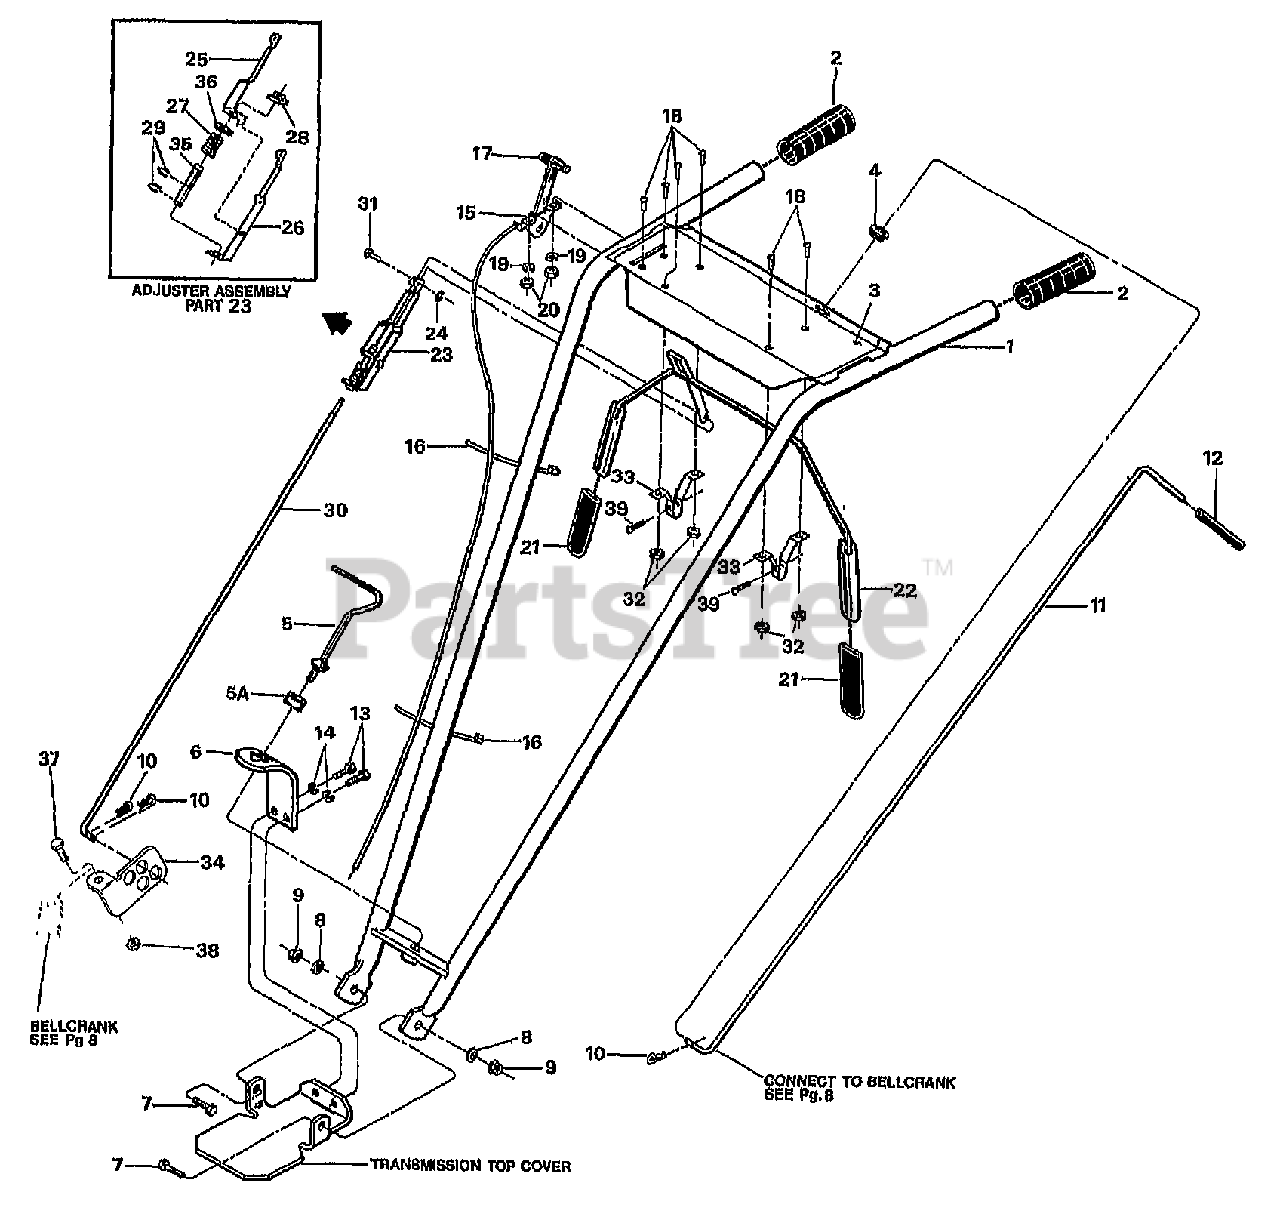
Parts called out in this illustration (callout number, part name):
1	ASSM-HANDLEBAR (INCL #2-5A)
2	GRIP-H/B 1" PONY/P-J OPC
3	DECAL-CONTROL PANEL OPC
4	BUSHING-NYLON (PART OF OPER CNTL PANEL)
5	ASSM-STUD H/B (HEIGHT ADJUSTMENT)
5A	WASHER-1.0X.38X.375 (USED WITH #5)
6	PLATE-HANDLEBAR HEIGHT ADJUST
7	SCR-HH 3/8-16X1.0 G5 ZP (HANDLEBAR ATTACH)
8	WASHER-FLAT 3/8 SAE (HANDLEBAR ATTACH)
9	NUT-LOCK 3/8-16 NYLON ZP (HANDLEBAR ATTACH)
10	PIN-CLIP .08
11	ROD-REV W/GRIP OPC - COMPLETE (INCL. GRIP #9198)
12	GRIP-CONTROL ROD
13	SCR-HH 3/8-16X.75 G5
14	WASHER-LK .375
15	CABLE-THROTTLE JR OPC
16	TIE-RED (PLASTIC)
17	KNOB-THROTTLE CABLE
18	SCR-RH M10-32X.5 MACH
19	WASHER-LK M10
20	NUT-HH M10-32X.125
21	GRIP-PADDLE SM FRAME OPC
22	BAIL W/GRIPS OPC (INCL. 2 GRIPS, #21)
23	ASSM-ADJUSTMENT OPC (INCL. 25-27, 29, 35-36)
24	RING-KLIP .188 DIA
25	ADJUSTER-RT SIDE OPC
26	ADJUSTER-LT SIDE OPC
27	SPRING-ADJUSTER OPC
28	WELDNUT 5/16-18
29	RING-KLIP .500 ZINC
30	ROD-CONTROL OPC
31	ASSM-PIN & CLIP (SMALL FRAME)
32	NUT W/LKWASHER #10-32 ZP
33	BRACKET-BAIL OPC
34	SWIVEL-SMALL FRAME
35	BUSHING-.5X.334X2.88
36	WASHER-.75X.51X.06 ZP
37	SCR-HH 1/4-20X.75 G5 ZP
38	NUT-LK 1/4-20
39	SCR-HWH 1/4-20 X .5 STH
